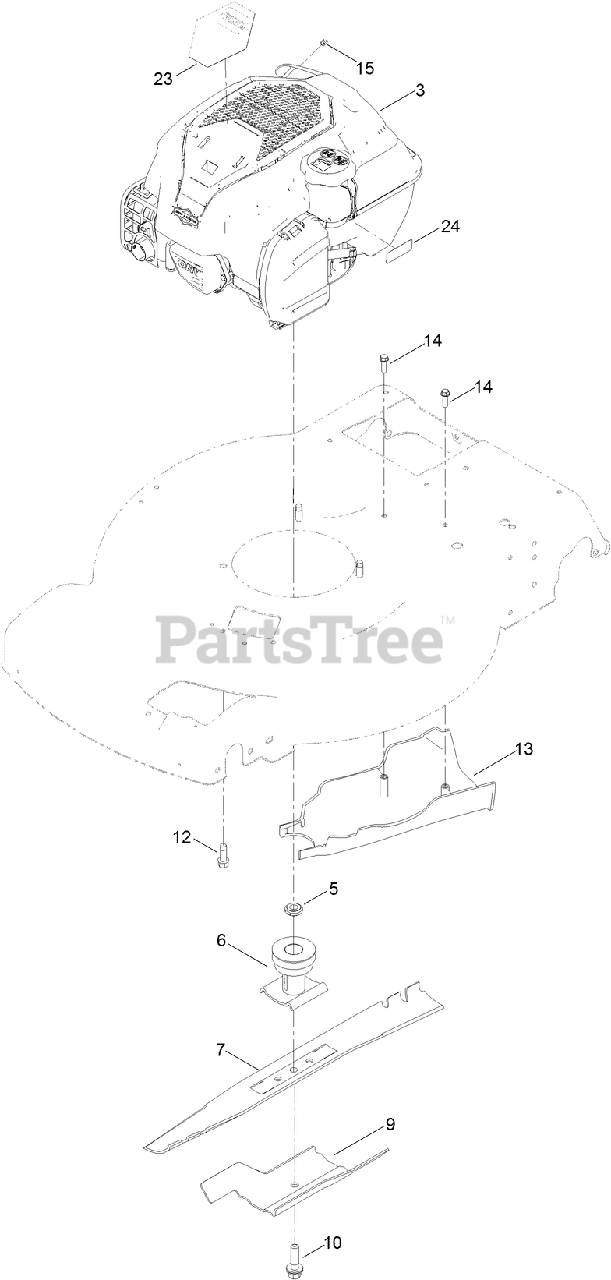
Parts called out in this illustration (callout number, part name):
5	SPACER-DRIVER
6	DRIVER-BLADE
9	ACCELERATOR-BLADE
10	BOLT-BLADE
12	SCREW-TAPTITE
13	COVER-BELT, REAR
14	SCREW-HWH
15	STOP-ROPE
23	DECAL-SHROUD
24	DECAL-LEVEL, FUEL
